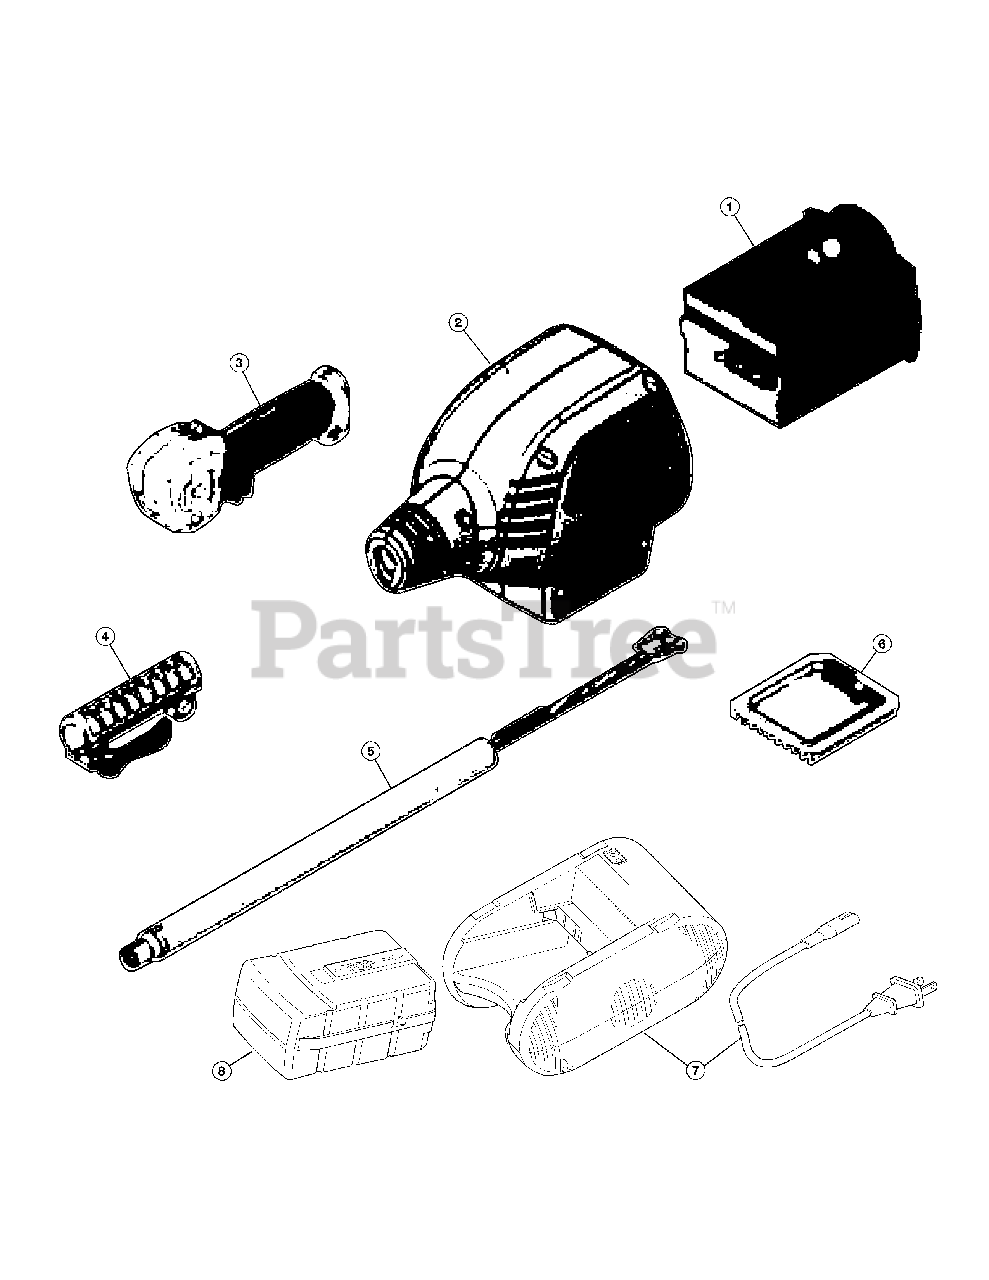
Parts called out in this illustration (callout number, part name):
1	Power Sleeve Assembly
2	Power Housing Assembly
3	Blower Grip Handle Assembly
4	Drive Unit Sleeve Clamp Assembly
5	Drive Unit Tube Cable Assembly
6	Power Lok Controller Assembly
7	Charger
8	Battery
